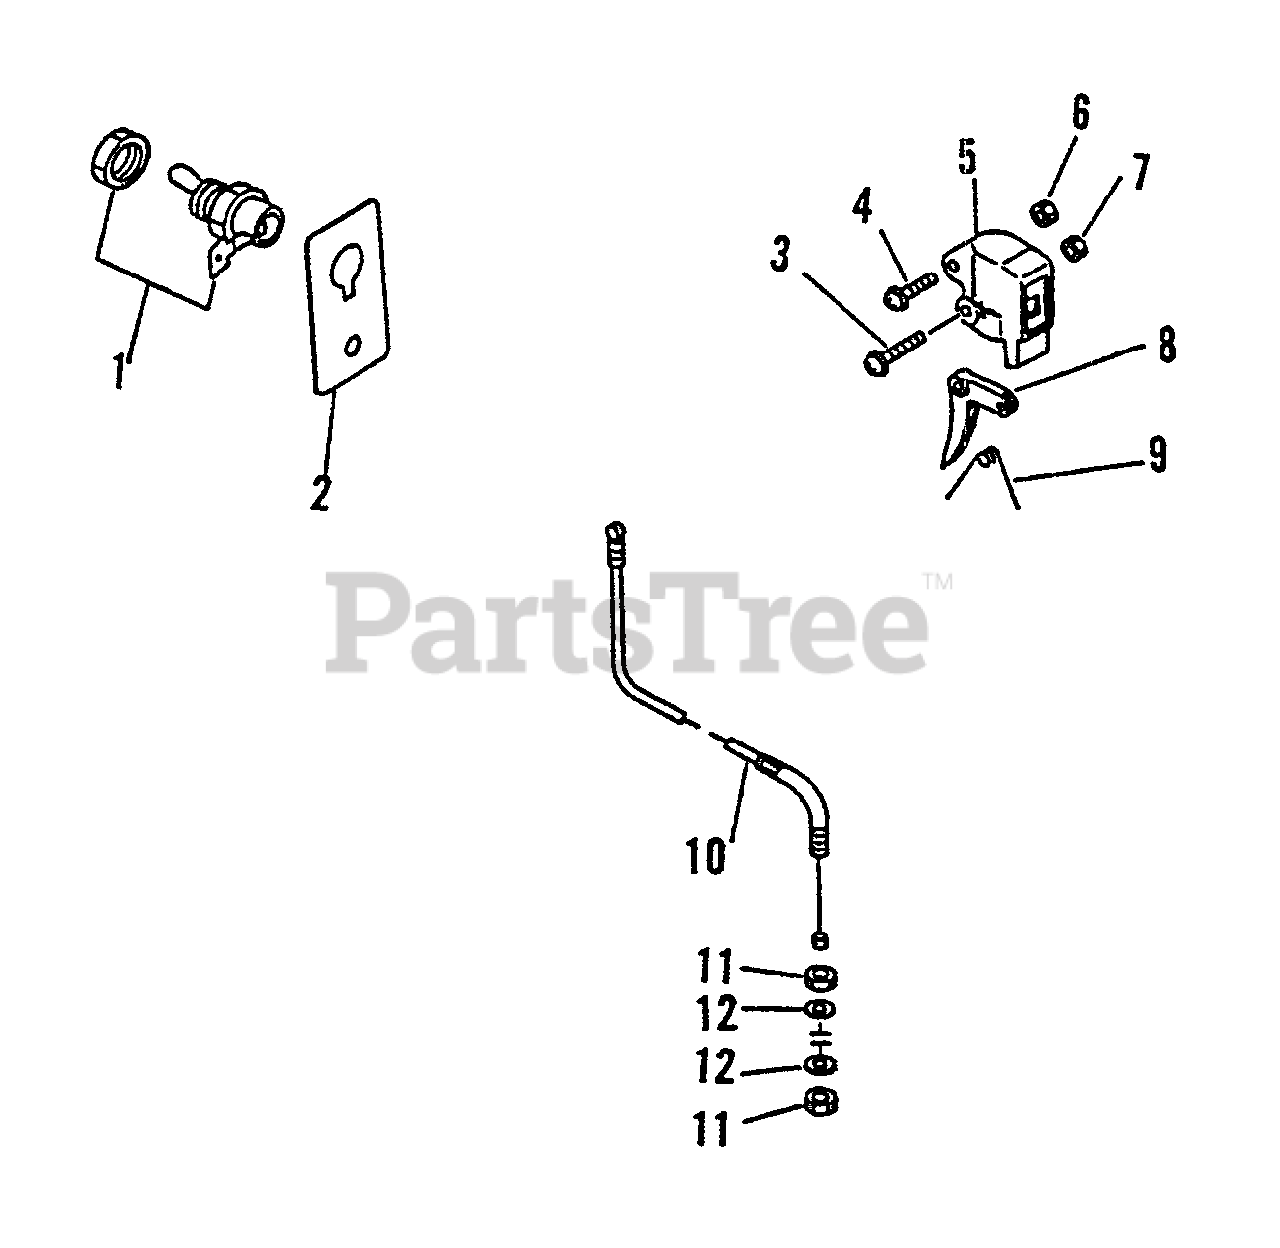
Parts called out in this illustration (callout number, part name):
1	IGNITION SWITCH KIT
2	BRACKET, SWITCH
3	SCREW - 5X30
4	SCREW - 5X28
5	BRACKET, TRIGGER
7	LOCKNUT - 5
8	TRIGGER, THROTTLE
9	SPRING, TRIGGER
10	CABLE, THROTTLE
10	CABLE, THROTTLE - B
12	LOCKWASHER - 6
